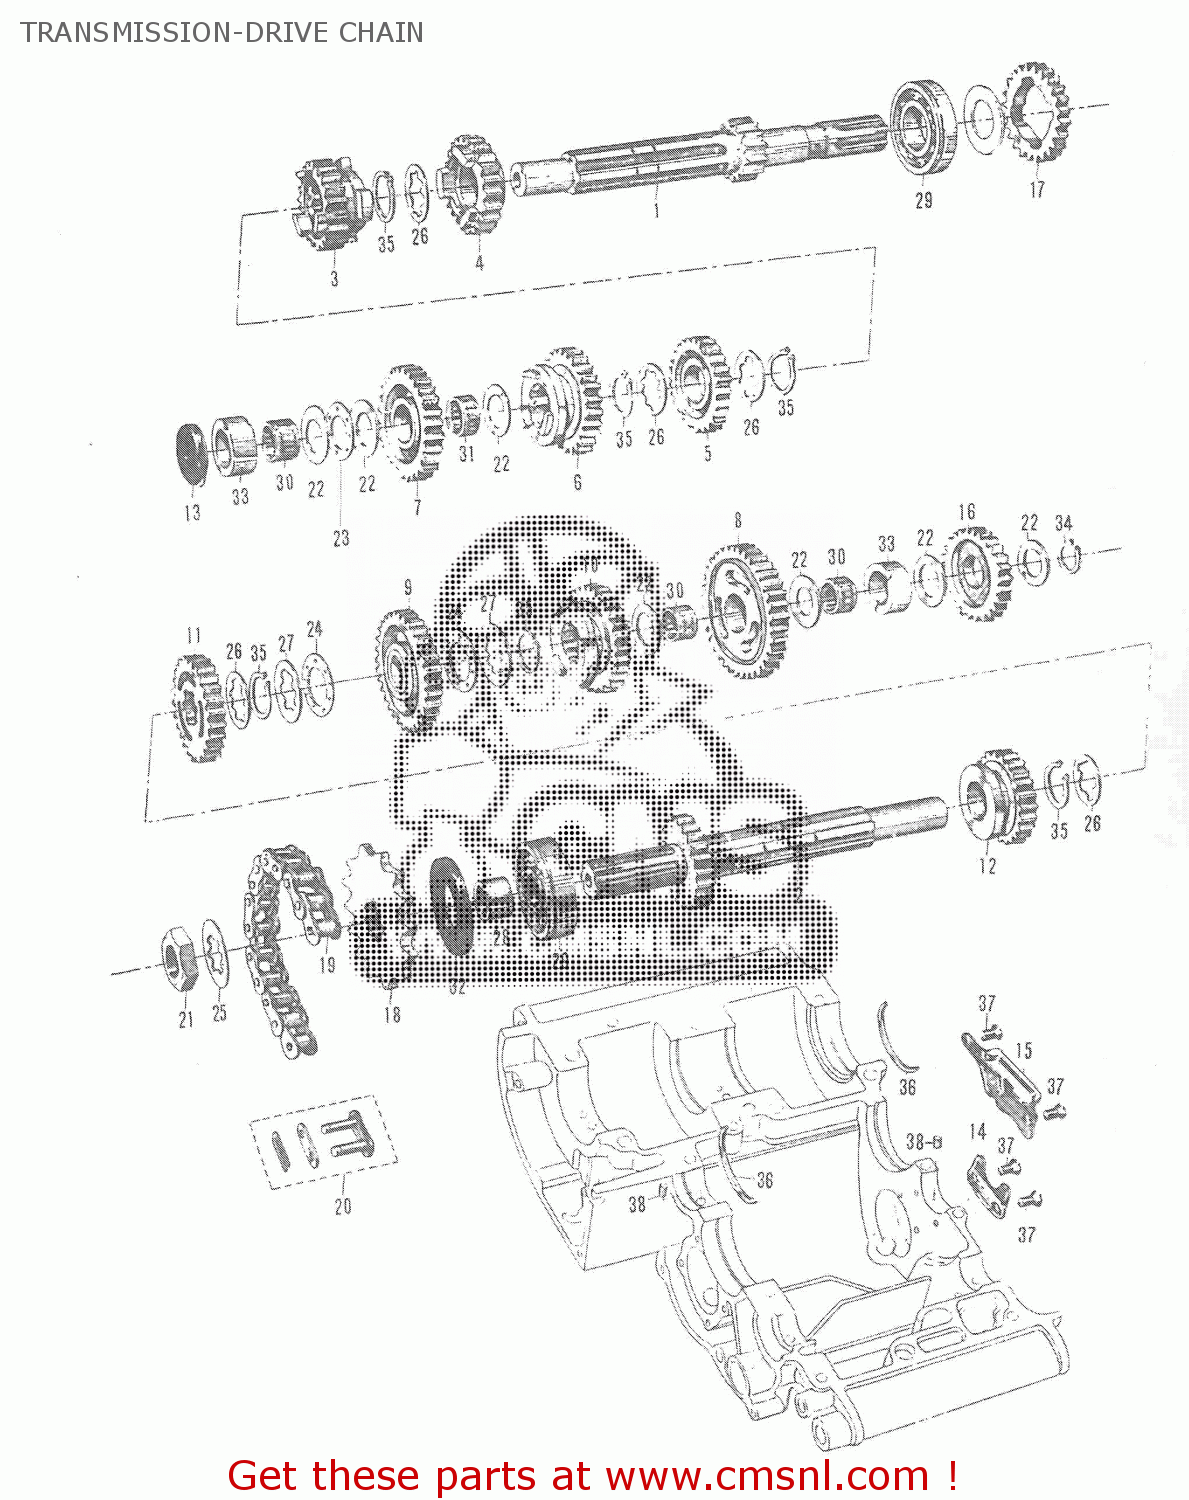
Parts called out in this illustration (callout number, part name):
1	COUNTERSHAFT
2	DRIVE SHAFT
3	SECOND PINION
4	THIRD PINION
5	FORTH PINION
6	FIFTH PINION
7	TOP PINION
8	LOW GEAR
9	SECOND GEAR
10	THIRD GEAR
11	FORTH GEAR
12	5TH DRIVEN GEAR
13	COUNTERSHAFT BUSHING RETAINER
14	RETAINER,DRIVESHAFT
15	PLATE,OIL RESERVOIR
16	GEAR,KICK STARTER IDLE
17	GEAR,KICK STARTER DRIVE
18	ENGINE SPROCKET
19	DRIVE CHAIN ASS'Y
20	CHAIN JOINT ASS'Y
21	NUT
22	WASHER
23	WASHER
24	SECOND GEAR INNER THRUST WASHER
25	WASHER,LOCK
26	WASHER,LOCK
27	2ND DRIVEN GEAR OUTER THRUST W (TC250; O.D. =34(1.34), T =1.0(0.
28	ENGINE SPROCKET SPACER
29	BEARING(20X52X15)
30	BEARING(17X21X12.8)
31	BEARING(17X21X9.8)
32	SEAL,OIL(25X52X7)
33	BUSHING
34	CIRCLIP
35	CIRCLIP
36	C-RING
37	CROSS HEAD SCREW
38	DOWEL PIN
